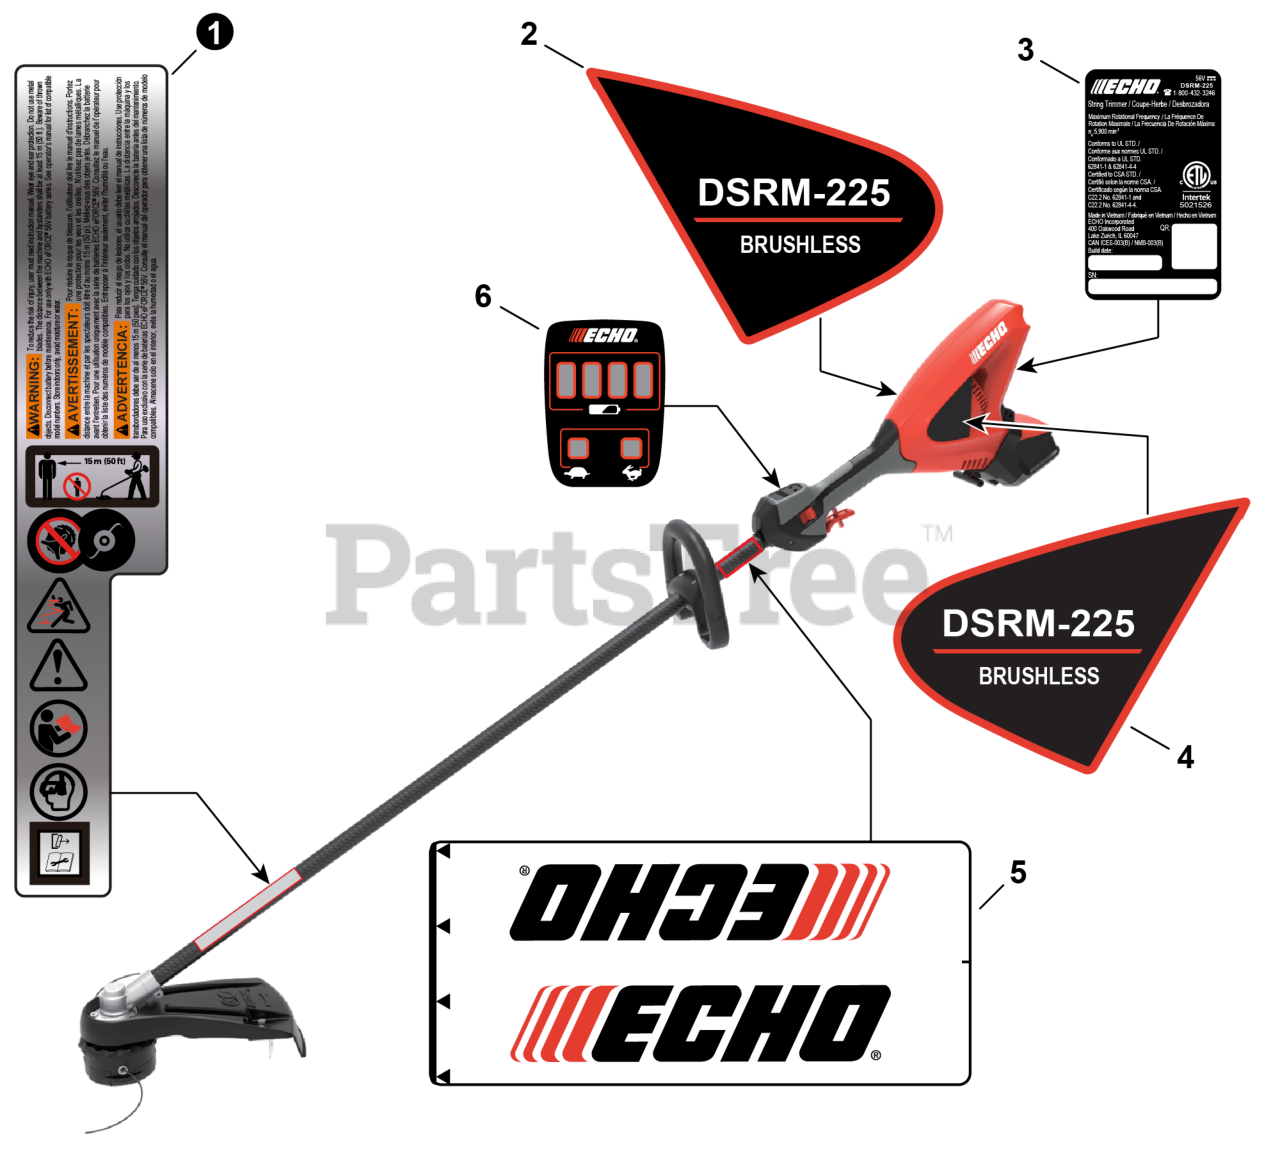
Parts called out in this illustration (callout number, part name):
1	LABEL, WARNING
2	LABEL, MODEL - RIGHT
3	LABEL, DATA
4	LABEL, MODEL - LEFT
5	LABEL, HANDLE
6	LABEL, LED DISPLAY
